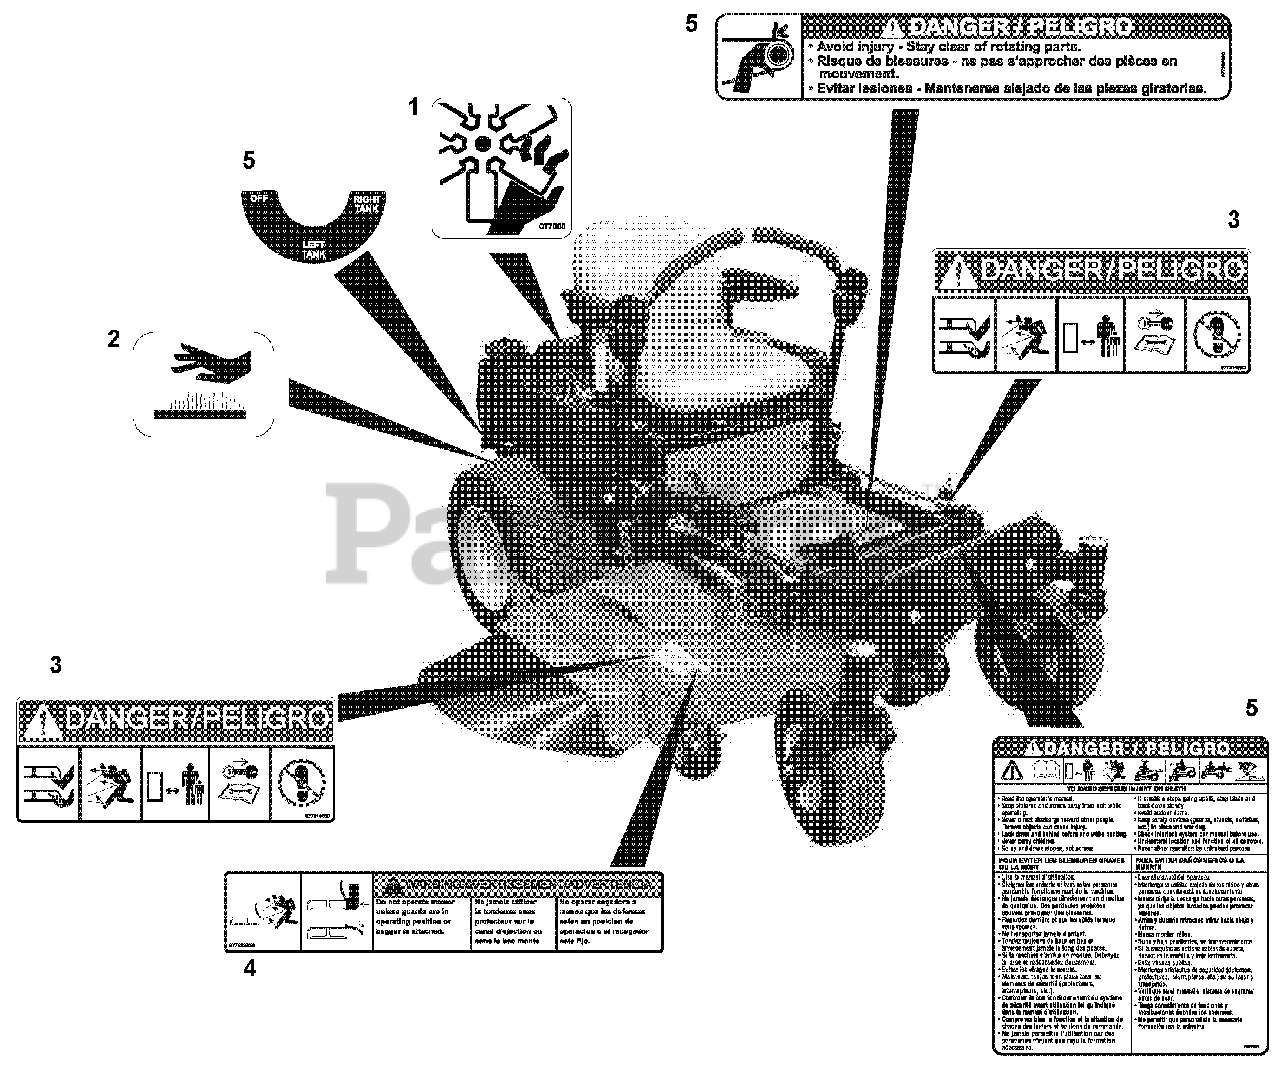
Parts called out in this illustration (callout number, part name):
1	DECAL, DANGER FAN
2	DECAL, HOT SURFACE
3	DECAL, MOWER PAN DANGER
4	DECAL, WARNING
5	GROUP, DECAL
